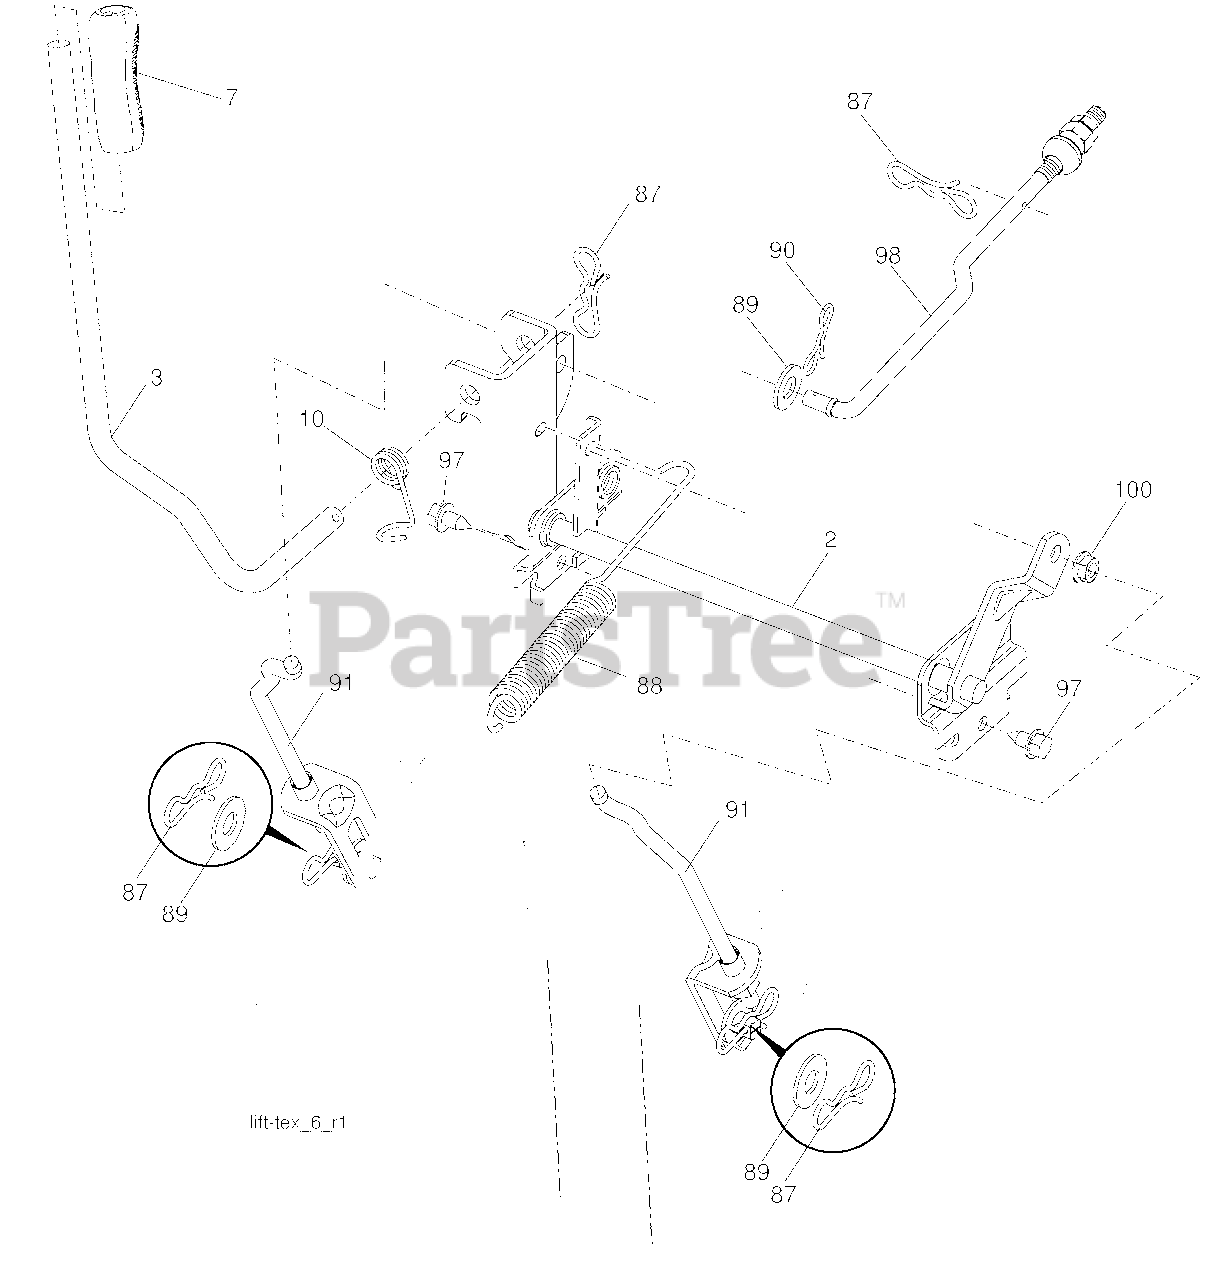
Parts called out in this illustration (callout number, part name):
2	Shaft Asm., Lift
3	Lever Asm., Lift RH
7	Grip, Lever
10	Spring Torsion
87	Pin Cotter 7/16 Bow Tie Lock
88	Spring Lift Assist
89	Washer Clear Zinc
90	Pin Cotter 5/16 Bow Tie Lock
91	Link Lift Susp Mower Rear
97	Screw 3/8-16 x .75 Smgml Tap/R.Z
98	Link Lift Susp. Front Mower
100	Nut Centerlock 3/8 -16 unc
